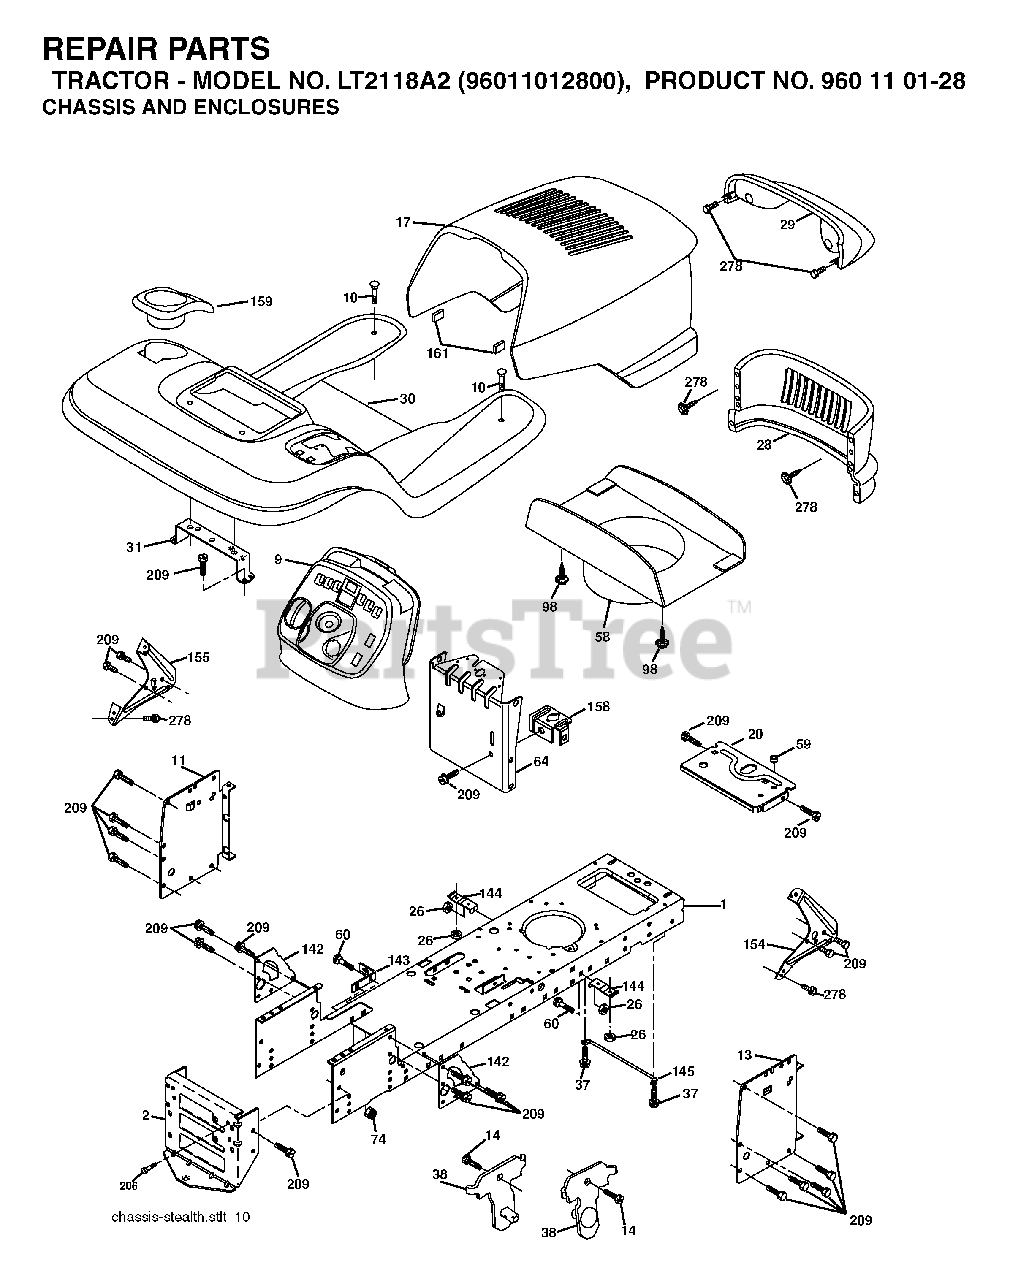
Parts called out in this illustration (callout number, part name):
1	CHASSIS STAMPING
2	DRAWBAR, 12GA
10	BOLT D
13	PANEL DASH RH
26	NUT
38	BRACKET.ASM.PIVOT.MOWER.REAR
58	DUCT HOOD
59	BUSHING.1.375OD
64	DASH LOWER
74	LOCKNUT
98	SCREW.WSHD.HEX10-32X5/8
142	PLATE REINFORCEMENT
143	BRACKET, SWAYBAR CHASSIS
144	BRKT, FOOT REST
145	ROD PIVOT CHASSIS/HOOD
161	EXTRUSION BUMPER
206	SHOULDER BOLT 5/16-18TT
209	SCREW, 3/8-16X3/4
278	SCREW
